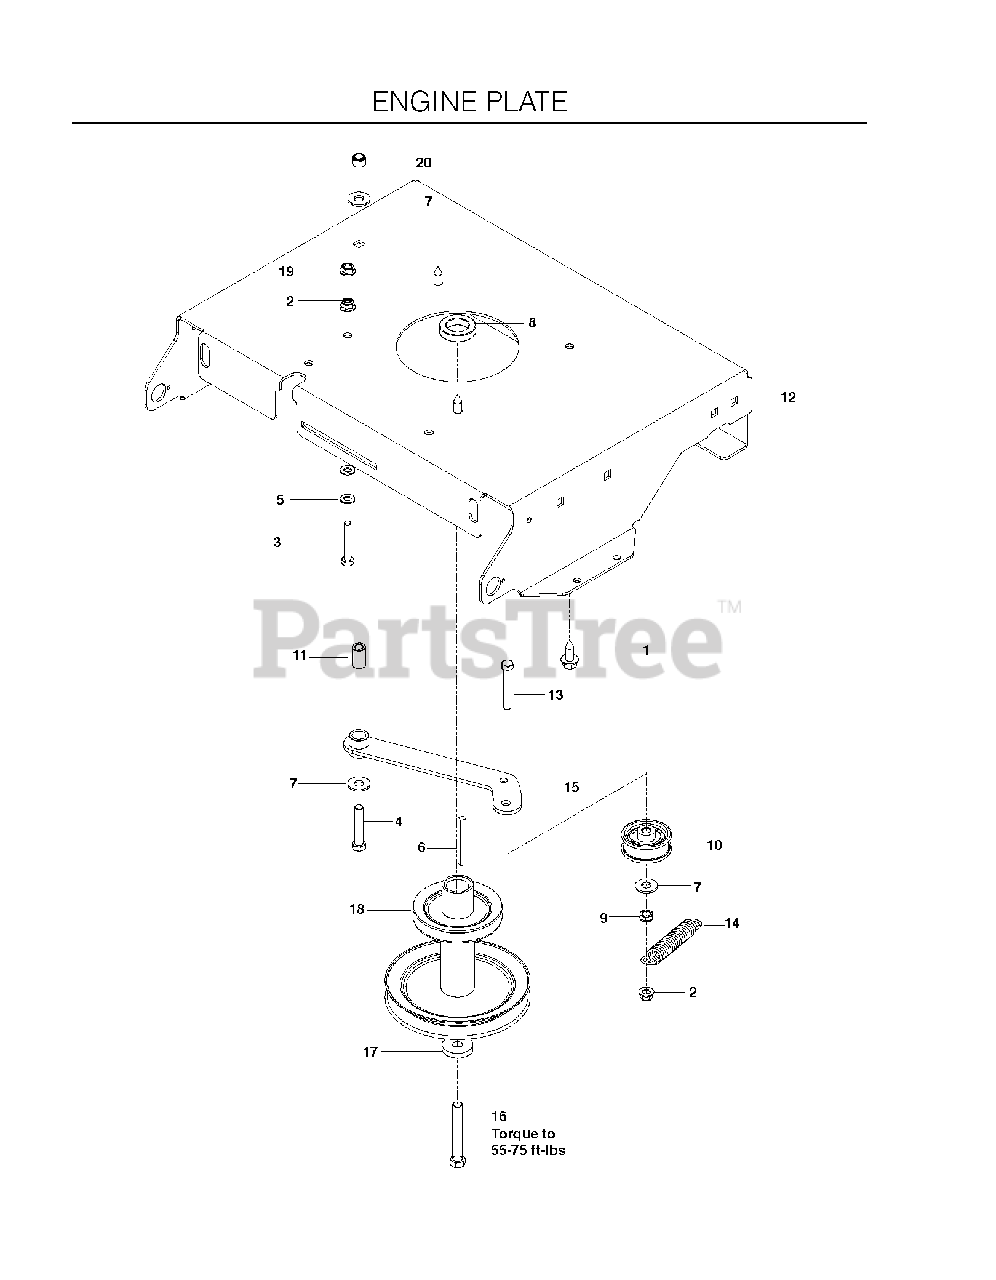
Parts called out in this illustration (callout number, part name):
1	HHFS 3/8-16 X 1.0 THD FORMING
2	5/16-18 NYLOC FLANGE NUT
3	HCS 5/16-18X2
4	HCS 3/8C X 2
5	FLAT WASHER 5/16 SAE
6	KEY 1/4 SQ X 2-1/2
7	WASHER 3/8 FLAT
9	NUT HEX 3/8-16 NYLON, THIN
10	PULLEY IDLER
11	BUSHING
12	PLATE, ENGINE, BLUE
13	CAPSCREW
14	SPRING - 3.50
15	IDLER ARM WLDMNT, BLACK
16	HCS 7/16-20 X 4 GR5 ZD
17	WASHER .43X1.38X.25
18	PULLEY, ENGINE 6.5
19	NUT 5/16C WHIZ
20	NUT HEX 3/8-16 NYLON, THIN
